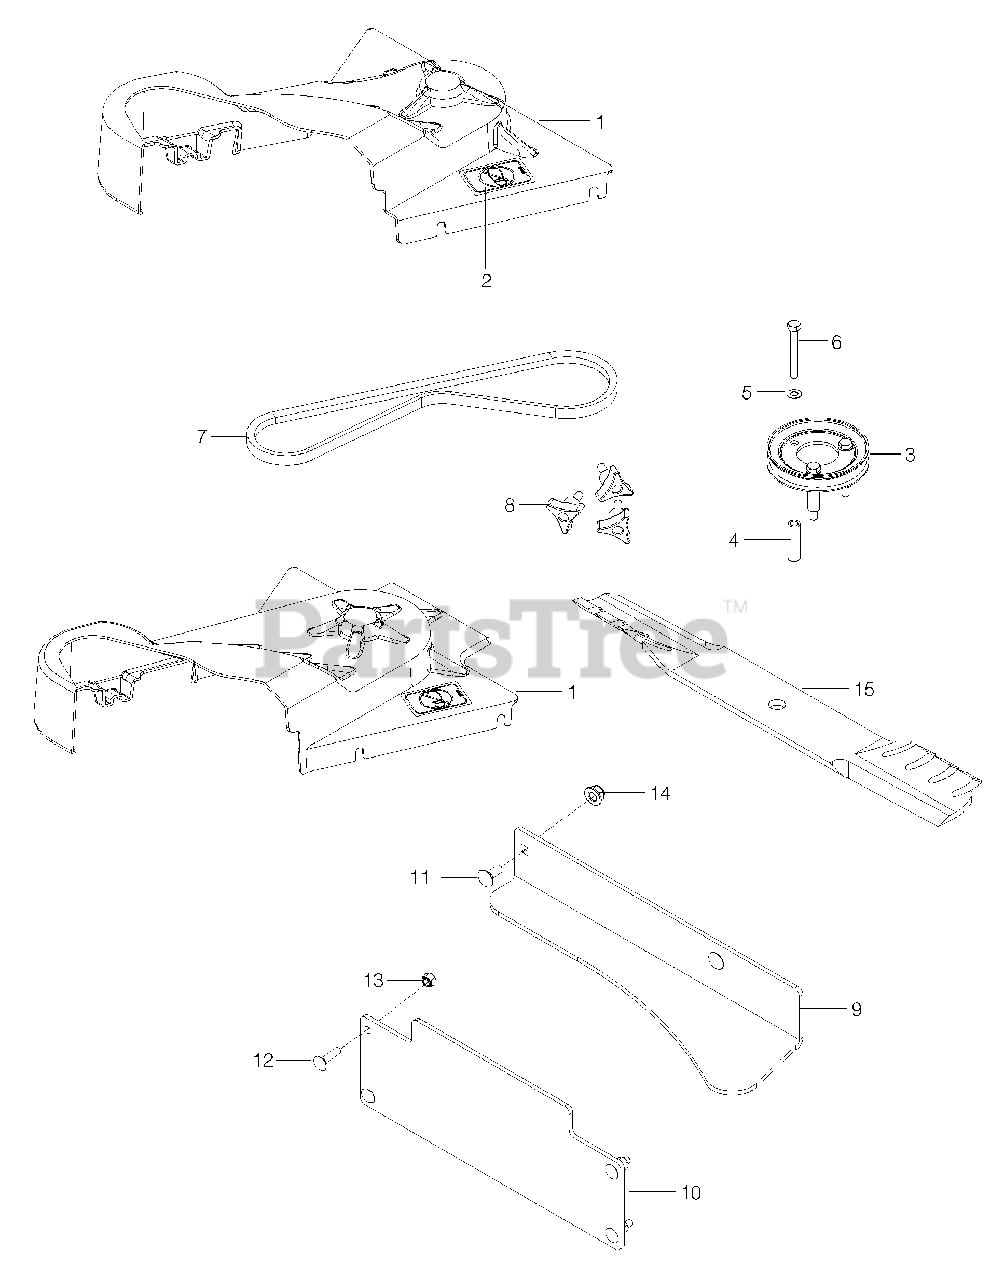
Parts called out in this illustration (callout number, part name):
1	Shield, Lower Belt, 54"
2	Decal, No Step
3	Pulley, Drive, 54"
4	Spacer, Pulley
5	Washer 5/16 Disc Spring
6	Hcs 5/16-18 X 2 1/2
7	Drive Belt 54"
8	Knob W/Stud
9	Baffle, Rh
10	Baffle, Lh
11	Rhsnb 1/4-20 X 1
12	Rhsnb 5/16-18 X 3/4
13	Nut 1/4-20 Hex Nyloc
14	Nut 5/16-18 Hex Flg Nyloc
15	Blade, 19" Gator 54" Collection
